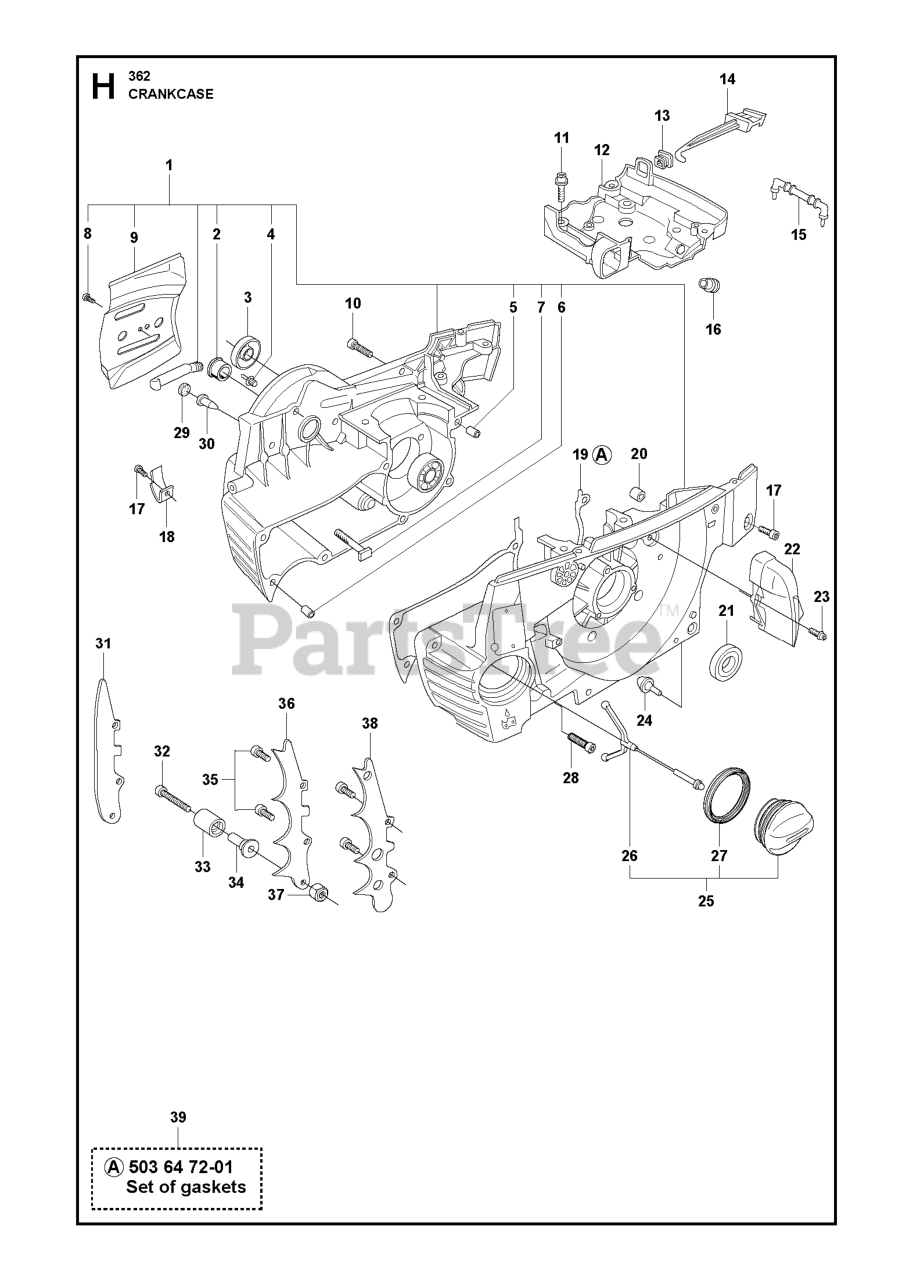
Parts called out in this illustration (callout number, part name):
1	DECAL, EURO SEVERING
1	CRANKCASE ASSY
2	DECAL, BELT DRIVE
3	EURO DECAL-BATTERY WARNIN6
4	DECAL, EURO WARNING
5	DECAL, NO STEP
6	DECAL, PROP. 65
7	DECAL, NASCAR
8	DECAL, MOBIL 1
8	SCREW CITXPANT
9	DECAL, HUSQVARNA LOGO 9.25"
9	BAR PLATE
9	PLATE
10	DECAL, EXHAUST
10	SCREW ITXSCM LIMITER M5X20/8 T
11	DECAL, LGE CROWN 7X6"
11	SCREW ITXSCFM M5X12 T27 12.9
12	HEIGHT ADJ DECAL
13	SERVICE DECAL
14	BELT ROUTING DECAL
15	DECAL, MOTION CONTROL
16	DECAL, CPSC
17	DECAL, FUEL VALVE
17	SCREW ITXSCM M5X20 T27 10.9 Z
18	DECAL - IZIZ4218
18	CHAIN CATCHER
23	SCREW ITXSCFM M5X12 T27 12.9
28	SCREW ITXSCM M5X32.3 T27 TIP
29	PLUG
30	VALVE-CHECK (DUCKBILL)
34	CHAIN CATCHER
35	SCREW ITXPANM M5X16 T27 10.9
36	FELLING DOG
38	FELLING DOG
39	GASKET SET
539107744	DECAL, IZ4818
539107745	DECAL - IZ4821
539107746	DECAL, IZ5223
